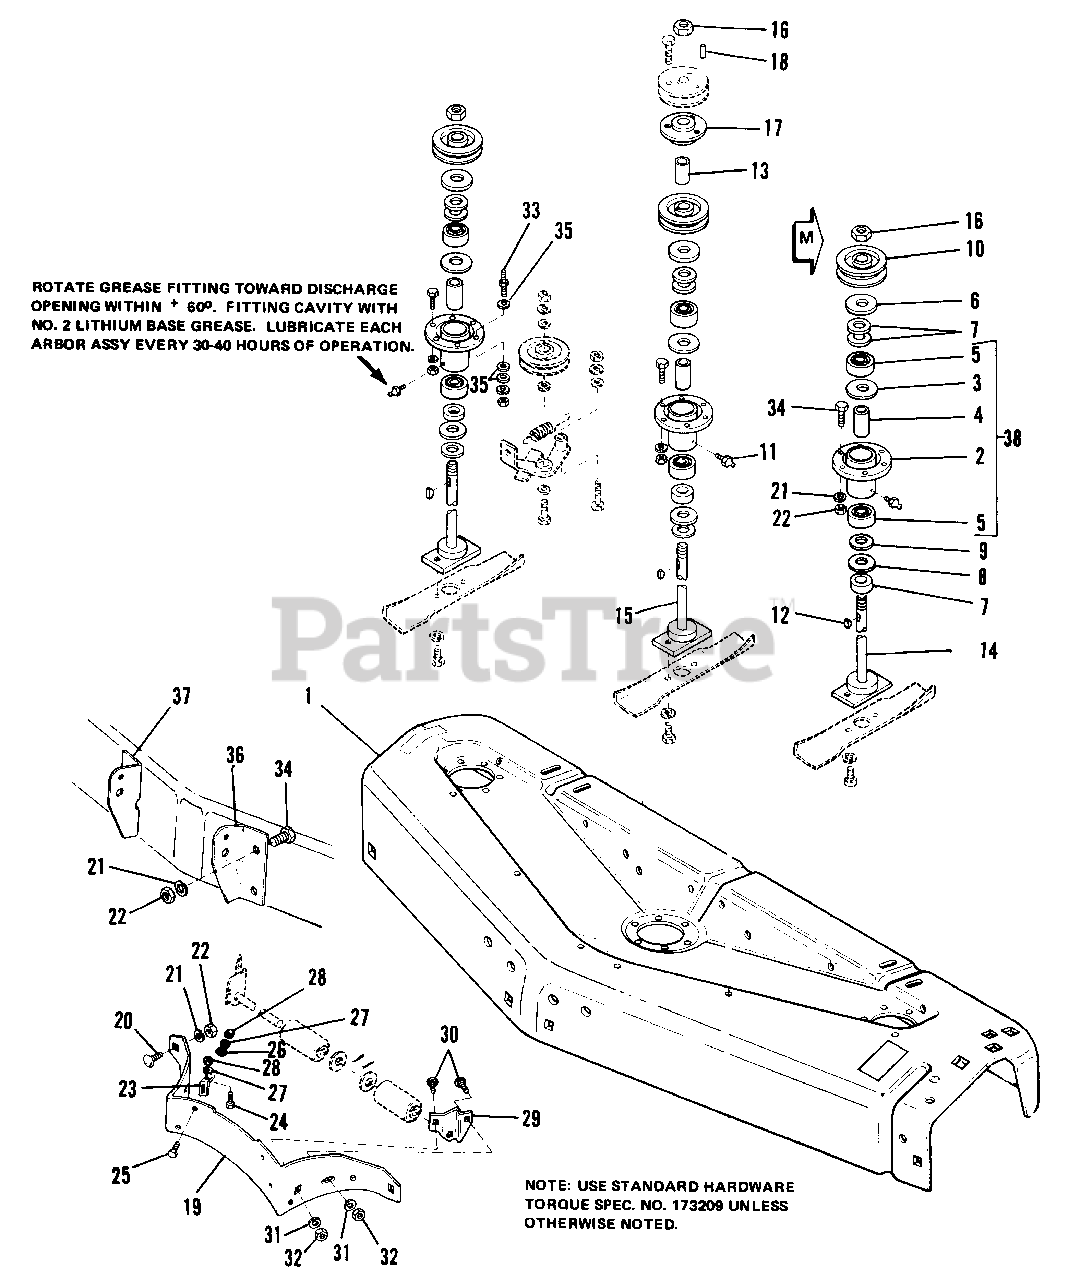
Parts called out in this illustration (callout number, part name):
1	HOUSING 42"
3	BACKING RING
11	FITTING, Grease
12	KEY, Woodruff, 3/16 x 5/8
14	ARBOR ASSY, Outer
15	ARBOR ASSY, Center
16	NUT, Full Hex Lock, 3/4-16
17	HUB, Pulley
20	CARRIAGE BOLT, 3/8-16 x 3/4
21	LOCKWASHER, 3/8
22	NUT, Hex Full, 3/8-16
23	CLIP, Baffle
24	SCREW, Self-Tapping, 1/4-20 x 7/8
25	CAPSCREW, Hex Hd., 1/4-20 x 5/8
26	WASHER, Plain, 1/4
27	LOCKWASHER, 1/4
28	NUT, Hex Full, 1/4-20
29	BRACKET, L.H. Roller
30	CARRIAGE BOLT., 5/16-18 x 3/4
31	LOCKWASHER, 5/16
32	NUT, Hex, 5/16-18
34	CAPSCREW, Hex Hd., 3/8-16 x 3/4
35	WASHER. Plain, 5/16
36	BRACKET, L.H.
37	BRACKET, R.H.
38	BEARING & TUBE ASSY
